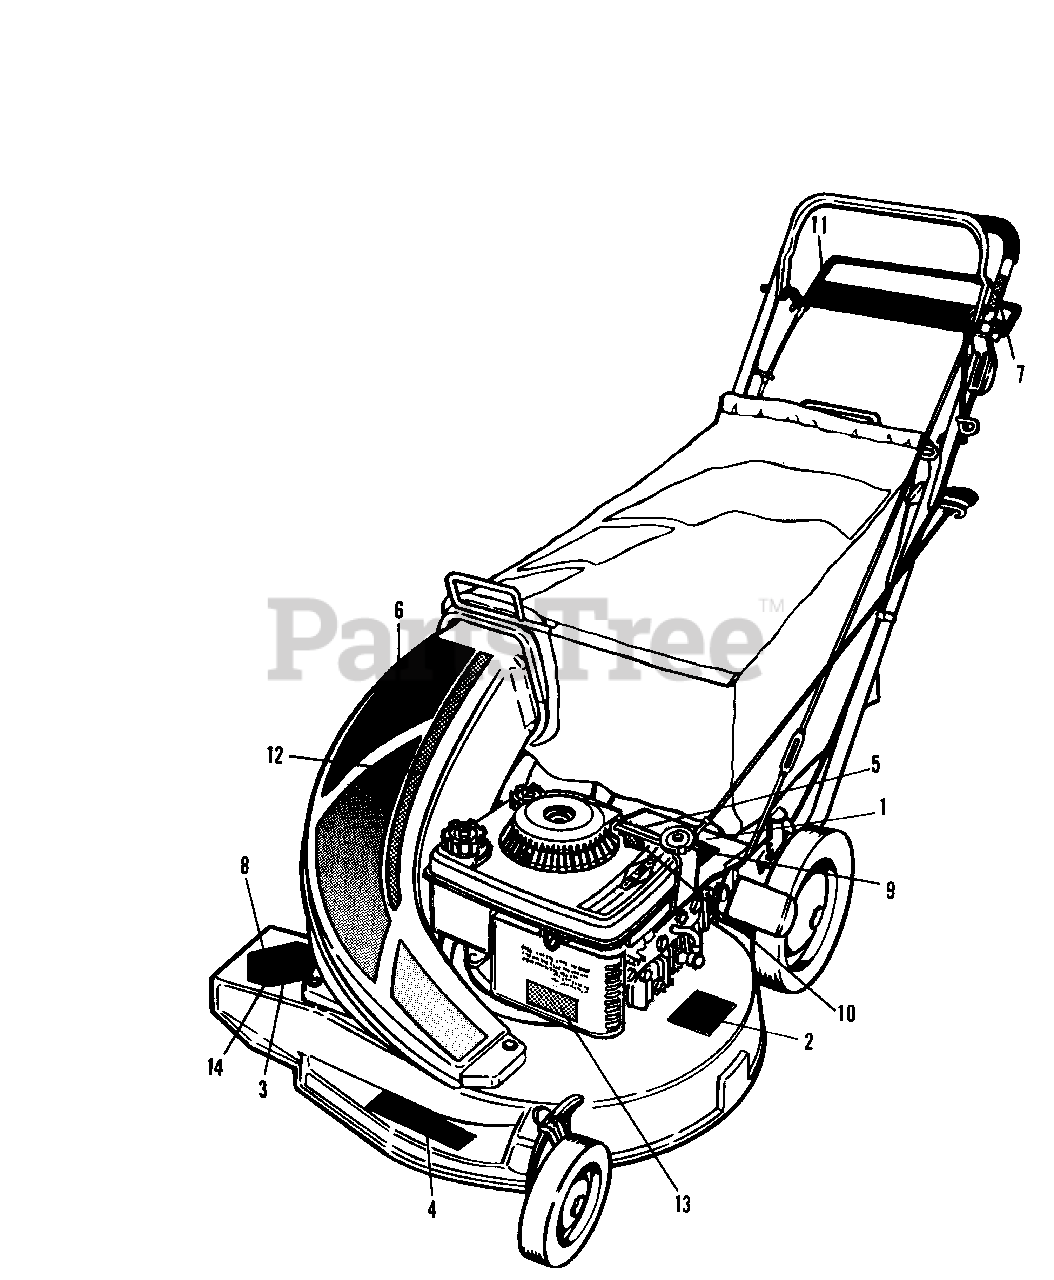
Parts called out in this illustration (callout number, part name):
1	DECAL, Speed Change
2	DECAL, Caution
3	OPEI
4	DECAL, Simplicity
5	DECAL, Two Speed
6	DECAL, Stripe Chute
7	DACAL, Handle
8	DECAL, Danger
9	DECAL, Hot Surface
10	DACAL, Blade Safety
11	DECAL, Control Panel
12	DECAL, Warning, on Chute
13	DECAL, 4.0 HP
14	DECAL, CPSC Blade Safety
